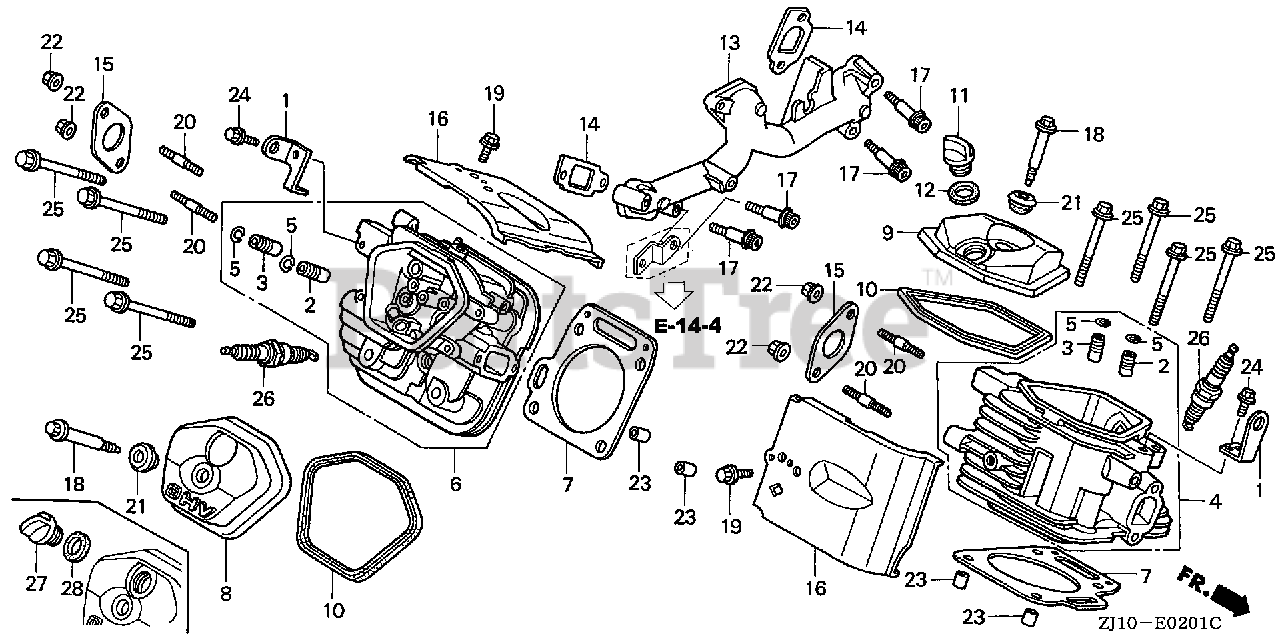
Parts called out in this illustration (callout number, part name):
1	HANGER, ENGINE
2	GUIDE, VALVE (OVER SIZE)
3	GUIDE, EX. VALVE (OVER SIZE)
4	CYLINDER HEAD (#1)
5	CLIP, VALVE GUIDE
6	CYLINDER HEAD (#2)
7	GASKET, CYLINDER HEAD
8	COVER, HEAD
9	COVER, HEAD FILLER
10	GASKET, HEAD COVER
11	CAP, OIL FILLER
12	GASKET, OIL FILLER CAP
13	MANIFOLD, IN.
14	GASKET, IN. MANIFOLD
15	GASKET, EX. PIPE
16	SHROUD, HEAD
17	BOLT, SOCKET (8X45)
18	BOLT, HEAD COVER
19	BOLT, FLANGE (6X14) (CT200)
20	BOLT, STUD (8X22)
21	WASHER, HEAD COVER
22	NUT, FLANGE (8MM)
23	PIN, DOWEL (12X20)
24	BOLT, FLANGE (8X20)
25	BOLT, FLANGE (10X80)
26	SPARK PLUG (BPR2ES) (NGK)
26	SPARK PLUG (J14CR-U) (DENSO)
26	SPARK PLUG (ZGR4A)
26	SPARK PLUG (J16CR-U) (DENSO)
26	SPARK PLUG (ZGR5A)
